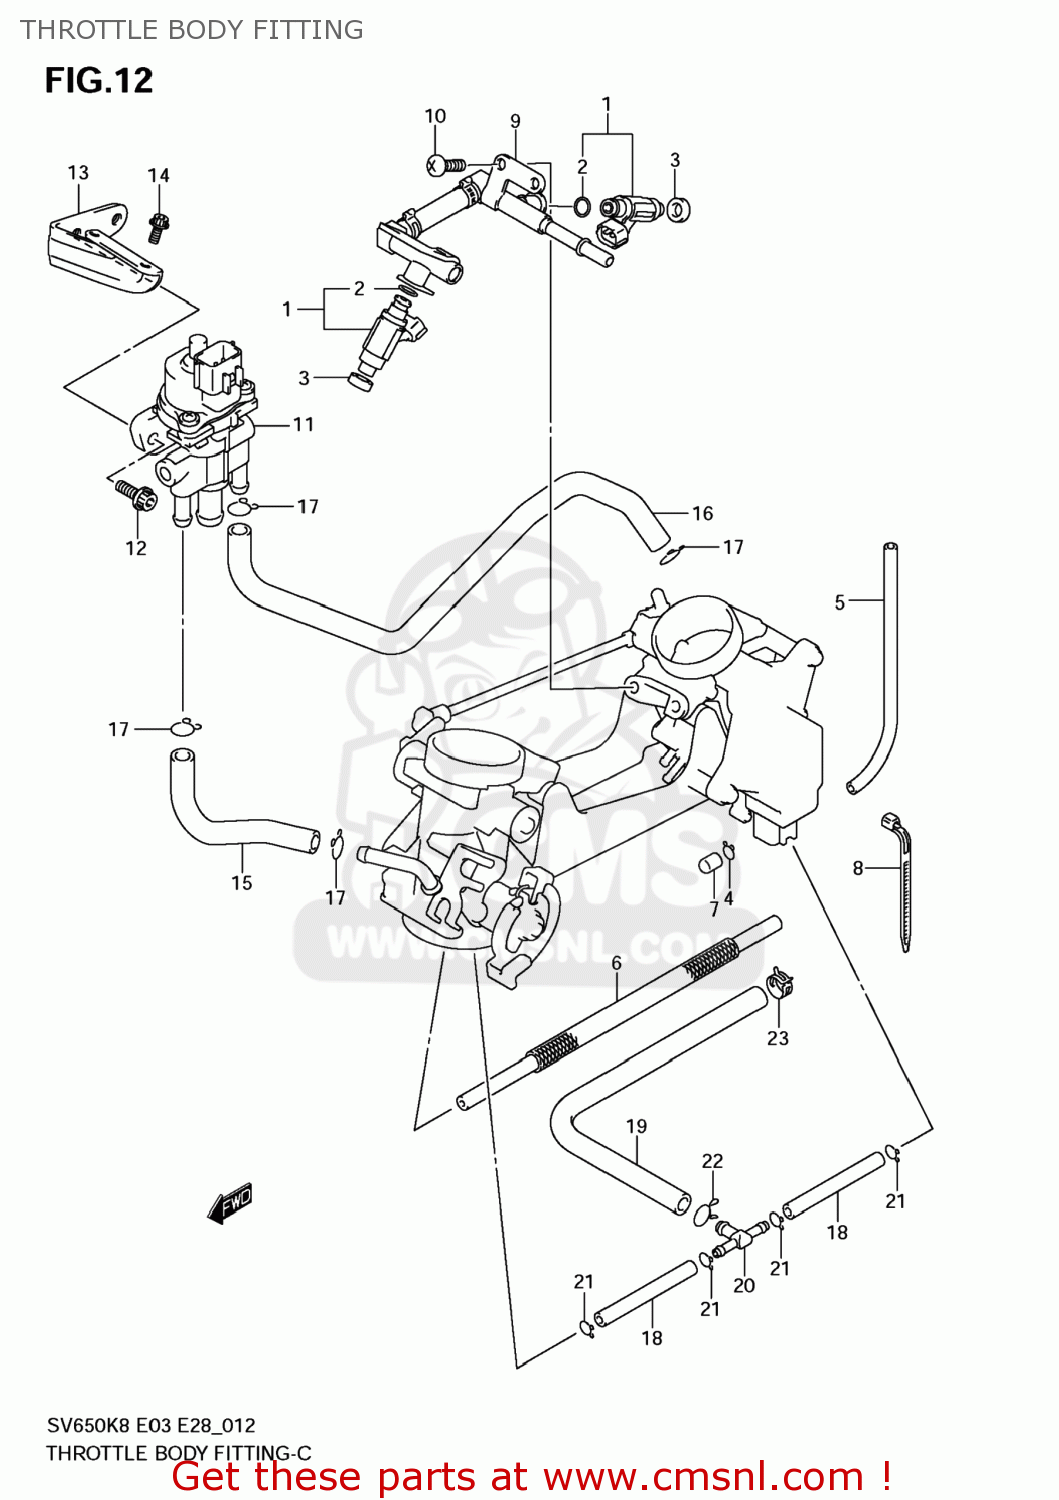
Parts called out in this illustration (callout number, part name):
1	INJECTOR ASSY
2	O RING
3	SEAL
4	CLIP
5	HOSE
6	HOSE
7	CAP
8	CLIP
9	DELIVERY PIPE ASSY
10	SCREW
11	VALVE,ISC
12	BOLT
13	BRACKET,ISC VALVE
14	BOLT
15	HOSE,ISC VALVE FR
16	HOSE,ISC VALVE RR
17	CLIP
18	HOSE
19	HOSE
20	NIPPLE
21	CLIP
22	CLIP
23	CLIP
